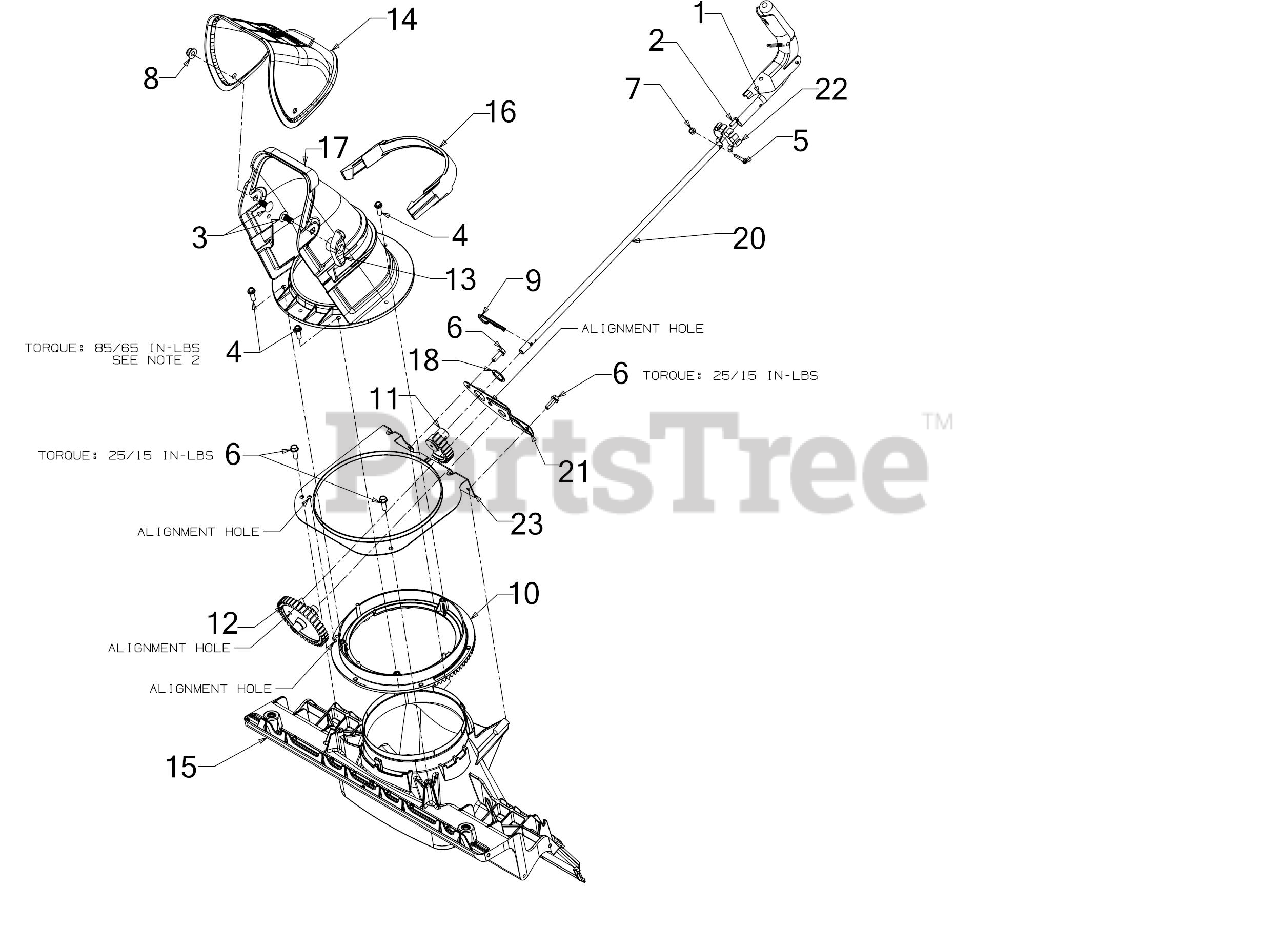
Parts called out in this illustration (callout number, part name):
1	CHUTE CONTROL ASSEMBLY
2	SCREW #8-16 x .50
3	CARRIAGE BOLT 5/16-18 x .75
4	SCREW 1/4 x .750
5	SCREW #8-32 x .875
6	SCREW 1/4-15 x .750
8	FLANGE LOCK NUT 5/16-18
9	COTTER PIN .125X2.
10	BEVEL GEAR 95T
12	SPUR-GEAR 40T
13	WING KNOB 5/16-18
14	UPPER CHUTE
15	CHUTE ADAPTER
16	CHUTE PLUG
17	LOWER CHUTE 6.5
18	FLAT WASHER .750X1.000X.060:HD
20	LOWER CHUTE CRANK ROD
21	GEAR PLATE
23	RETAIN GEAR BRACKET
